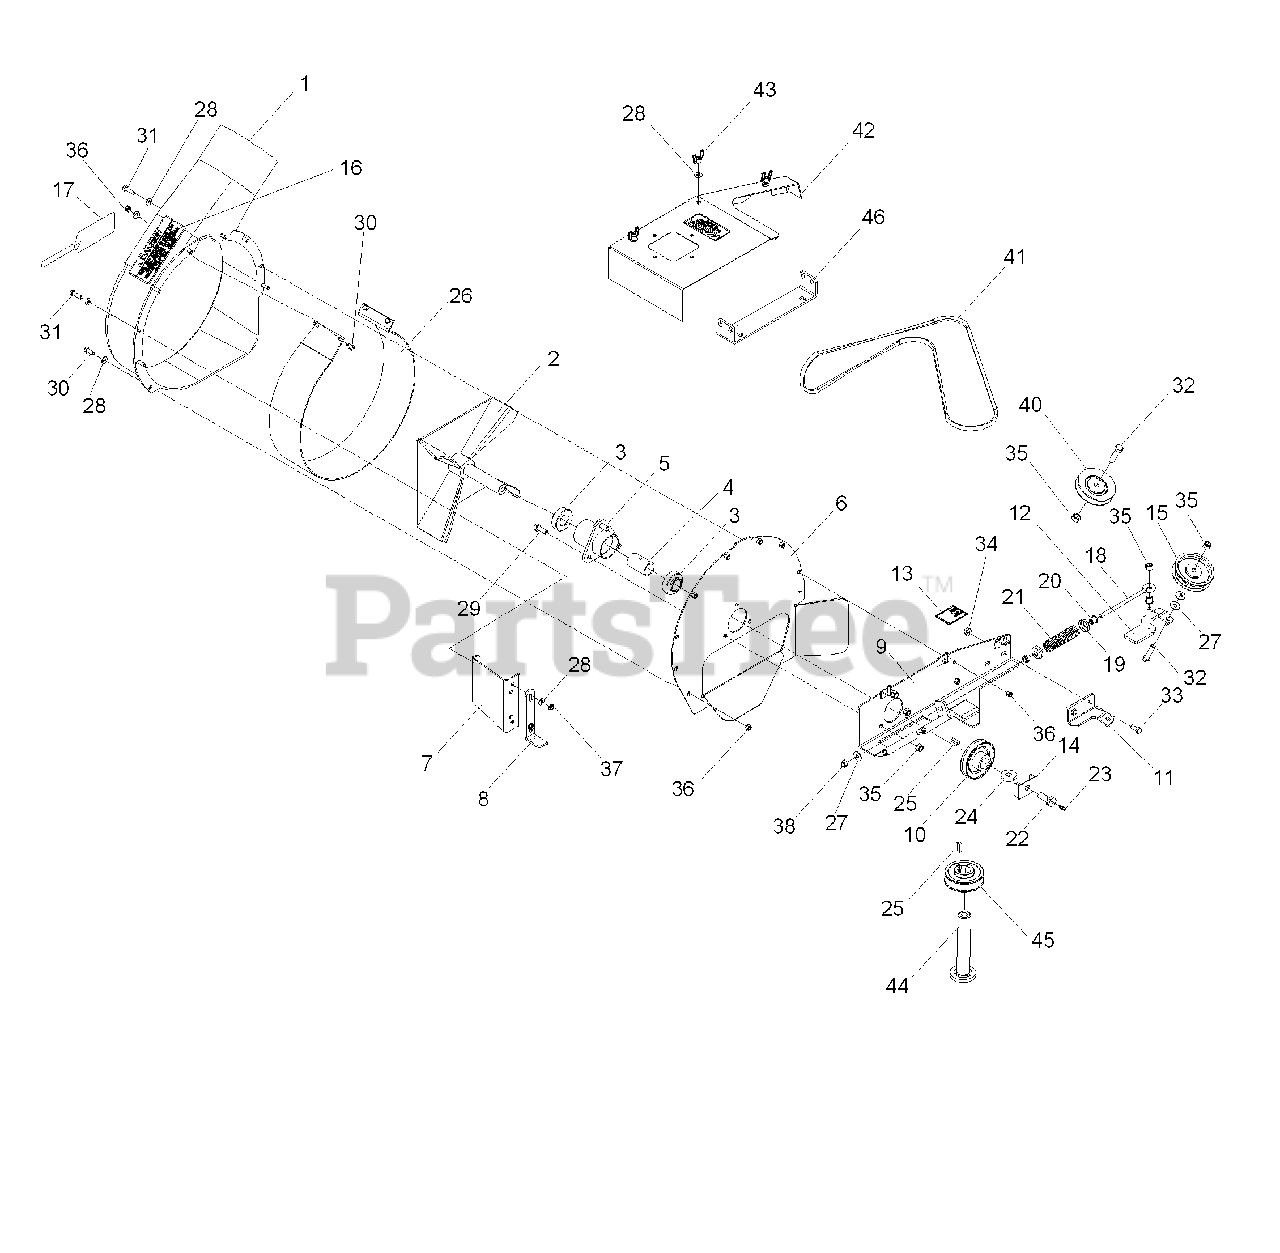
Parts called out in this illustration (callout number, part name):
2	FAN/SHAFT WLDT.
3	BEARING-ECC LOCK
4	SPACER 1 X 2.083
5	HUB WLDT-MACHINED
6	HOUSING PLATE
7	HOUSING GUARD
8	TIP GUARD
9	IDLER BASE WLDT.
10	PULLEY - 3.5
11	PULLEY BRKT.
12	PULLEY SLIDE WLDT.
13	DECAL, ROUTING 42"
15	PULLEY, IDLER 3 METAL
16	G.C.WARNING DECAL
17	DECAL, DIXON
18	EYE BOLT 5/16 X 6.00
19	SPRING RETAINER
20	FLIP-LOK BUSHING
22	HUB BOLT-DRILLED
23	ZERK, 3/16, DRIVE IN
24	WASHER .525 X 1.375 X .25
25	OUTER SHAFT KEY
26	SAND LINER
27	WASHER 5/16 FLAT
28	1/4` SAE FLAT WASHER
29	HCS 3/8C X 1
30	HCS 1/4C X 3/4 HCS
31	HCS 1/4C X 1
32	HCS 3/8C X 1 1/2
33	HCS 5/16C X 3/4
34	5/16-18 FLANGED L-NUT
35	NUT 3/8-16 NYLOC
36	NUT 1/4-20 NYLOC
37	JAM NUT 1/4C
38	NUT 5/16 NYLOC
39	HCS 3/8-16 X 1 3/4 GR5
40	PULLEY, IDLER 3 METAL
42	44 GUARD ASM
43	WING NUT 1/4
44	SHAFT LONG
45	V-PULLEY
46	BLOWER HINGE
